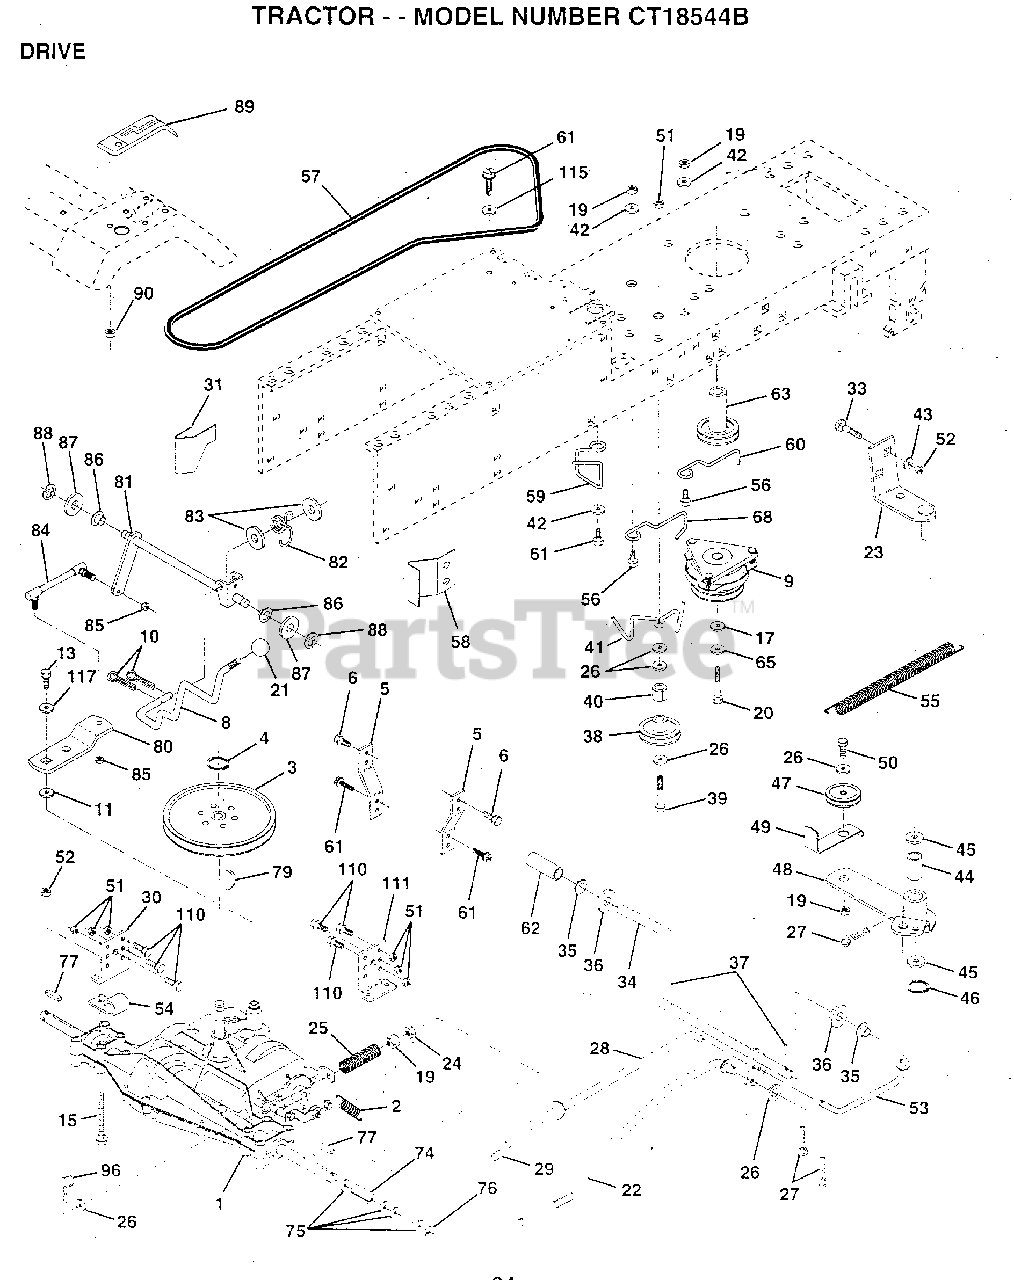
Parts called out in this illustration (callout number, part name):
1	TRANSAX. PRLES.
3	PULLEY TRANSAXLE
4	RING
5	STRAP TORQUE
6	SCREW
10	PIN COTTER 1/8
11	WASH-SHFT PLT LT
13	BOLT.1/4-28.W/PAT
15	BOLT.HX.FLG.5/16
17	WASHER
19	NUT
20	BOLT.7/16-20X4.25
21	CONTROL KNOB LT
22	ROD.ASM.BK.44.MWR
23	BRACKET.ASM.MTG
24	NUT
25	"SPRING,ROD BRAKE"
26	WASHER
27	COTTER PIN
28	ROD.BRAKE.PARK.LT
30	BRKT TRANS LH
31	KEEPER BELT LH
33	BOLT
34	SHAFT.PEDAL.FOOT
35	NYLON BEARING
36	WASHER LT
38	PULLEY.IDLER.FLAT
39	BOLT
40	SPACER T
41	BELT KEEPER LT
42	WASHER
43	WASHER T
44	"LY, BEARING"
45	WASHER LT
46	KLIP RING
48	ARM IDLER
49	RETAIN BELT
52	NUT
53	"LINK, CLUTCH T"
54	"CLIP,INSULATOR"
55	"SPRING, RETURN LT"
57	BELT.GRDRV.94.75
58	"KEEPER,BELT RH"
59	KEEPER BELT CNTSP
60	KEEPER BELT ENGLH
61	SCREW
62	PEDAL COVER T
63	PULLEY ENGINE
65	LOCKWASHER
68	"KEEPER,BLT ENG LT"
74	SPACER HYT
75	WASHER
76	E RING HYT
77	SQ KEY STD
80	"ARM,SHIFT"
81	"SHAFT,SHIFTER"
82	"SPRING,TORSION"
83	WASHER
84	"ROD,TIE "
85	NUT.CNT.LOCK.1/4
86	BUSHING
87	WASHER D
88	KLIP RING
89	CONSOLE SHIFTER
90	NUT
96	RETAINER M
100	WASHER M
111	BRKT TRANS RH
115	WASHER GT
117	WASHER PM
